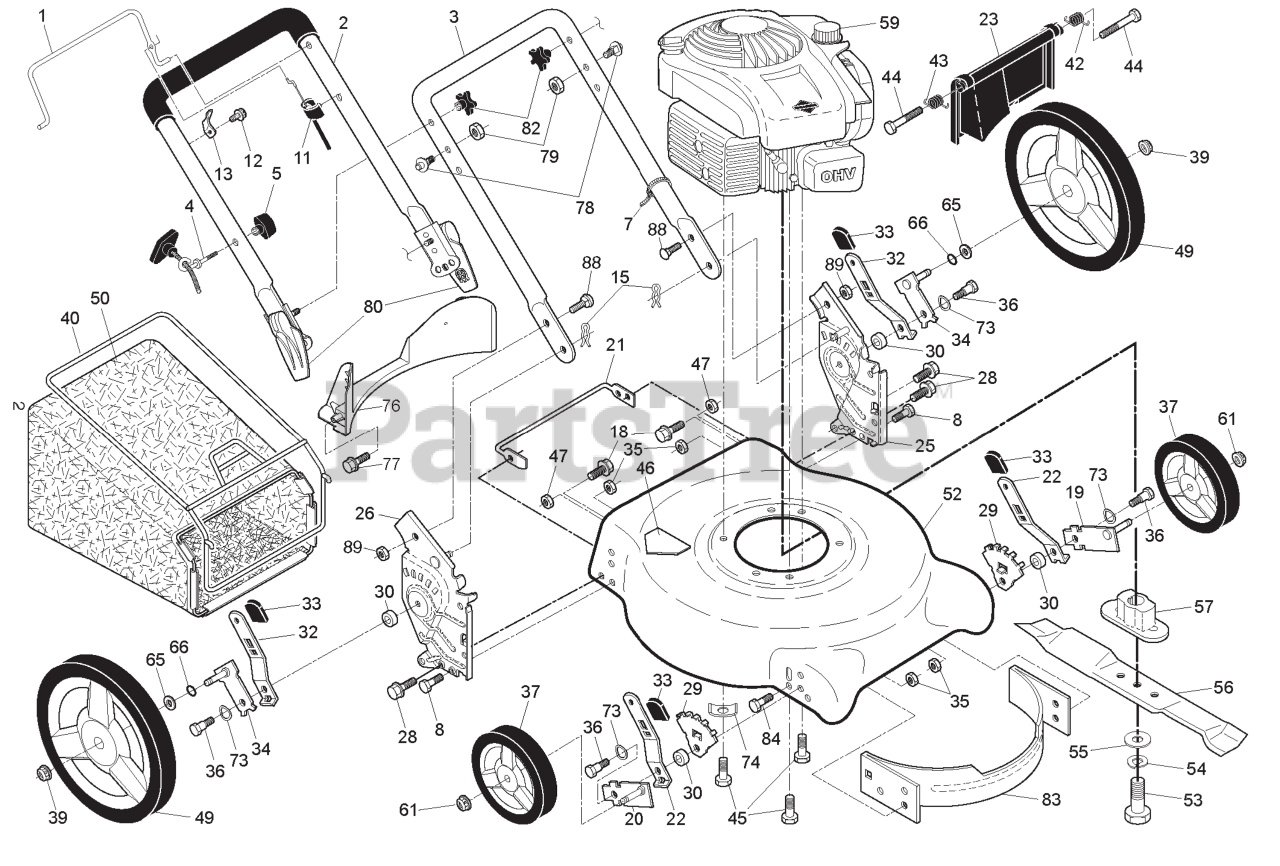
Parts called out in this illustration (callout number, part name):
1	42" DECK KIT
2	RP BOLT 5/16-18 X3/4 ZN/YEL GR
3	BRKT ASM SWAY BAR
4	BRACKET SWAY BAR 42" DECK
5	RETAINER-SPRNG RB
6	REAR SUSP ARM
8	BLADE BOLT
9	LOCKWASHER
10	WASHER.BLADE
11	BLADE 42", YTH 160
12	BEARING.BALL.#6204.(MANDREL)
13	SHAFT ASM VENT
14	HOUSING.MANDREL.VENTED (MACHD)
16	STRIPPER
18	BOLT
19	BOLT SHD 5/16-18
20	BAFFLE.VORTEX
21	LOCKNUT
22	STIFFENER BRACKET
23	DEFLECTOR BRACKET
24	CAP-SLEEVE LT
25	SPRING TORSION
26	NUT PUSH M
27	SHIELD DEFLECTOR
28	Washer 11/32 x 5/8 x 16 Ga SD
29	ROD.HINGE
30	SCREW THDROL ROLLING WASHER HD
31	WASHER
32	PULLEY/MANDREL
33	NUT
35	FASTENER.XMAS.TREE
36	FLAT IDLER PULLEY
37	WASHER
44	GUARD MANDREL LH BLACK
45	RETAINER M
46	SCREW.1/4-20X5/8
49	ROLLER ASSY
52	BOLT.SHOULDER.5/16-18
53	ARM
54	HARDENED WASHER
55	ARM IDLER 42" MOWER LT/YT
56	SPACER.RETAINER.MOWER
59	GUARD, BELT
67	KNOB T (3/8 HOLE)
68	BELT
90	BOLT
91	BRACKET LH (A)
92	NUT
93	Washer 1 17/32 X 7/8 X 16 Ga
94	NOSE ROLLER
95	BRACKET RH (B)
111	BRACKET WHEEL GAUGE LH 42" DK
112	BRACKET WHEEL GAUGE RH 42" DK
113	SCREW 5/16"
114	NUT
115	BOLT.CARR.5/16-18X1/2
116	BOLT M
117	WHEEL.GAUGE.STANDARD
118	LOCKNUT
119	WASHER.5/16.FLAT.STE.STD.
121	BRACKET.EXTRUDED.GAGE.WHEEL
128	WASHER FELT
129	WASHER
131	BOLT D
142	ARM SPRING BRAKE MOWER
143	BRACKET, ARM IDLER
144	DNO KEEPER.BELT.42".CLUTCH.CBL
145	PULLEY
146	BOLT, CARRIAGE IDLER
147	SPRING EXTENSION
148	IDLER RETURN SPRING
149	SPRING.RETAINER.YELLOW.ZINC
151	BRACKET.CLUTCH.CABLE
152	CLUTCH CABLE 42"
153	WASHER FLAT 3/8"
154	SPRING RETAINER
155	SPRING RETENTION LEVER
156	SPACER.CLUTCH.CABLE
157	ROD CLUTCH CABLE 3/8"
158	SCREW LT
